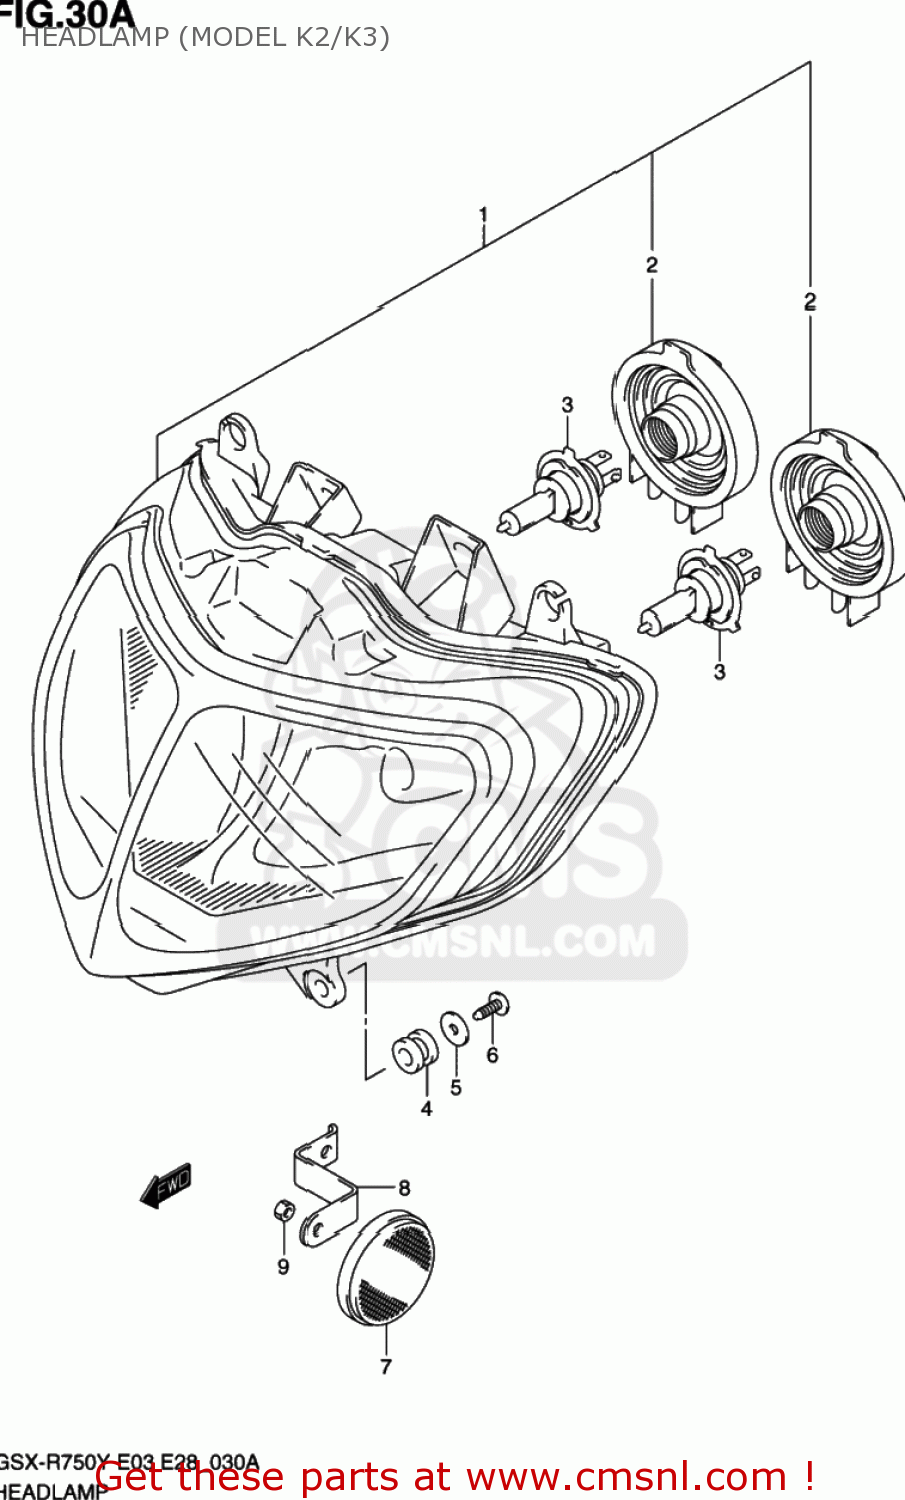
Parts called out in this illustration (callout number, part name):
1	HEADLAMP ASSY
2	COVER,SOCKET
3	BULB(12V60/55W,H4)
4	CUSHION
5	WASHER(5.5X18X1)
6	SCREW
7	REFLECTOR,REFLEX
8	BRACKET,FR SIDE RR
9	NUT
